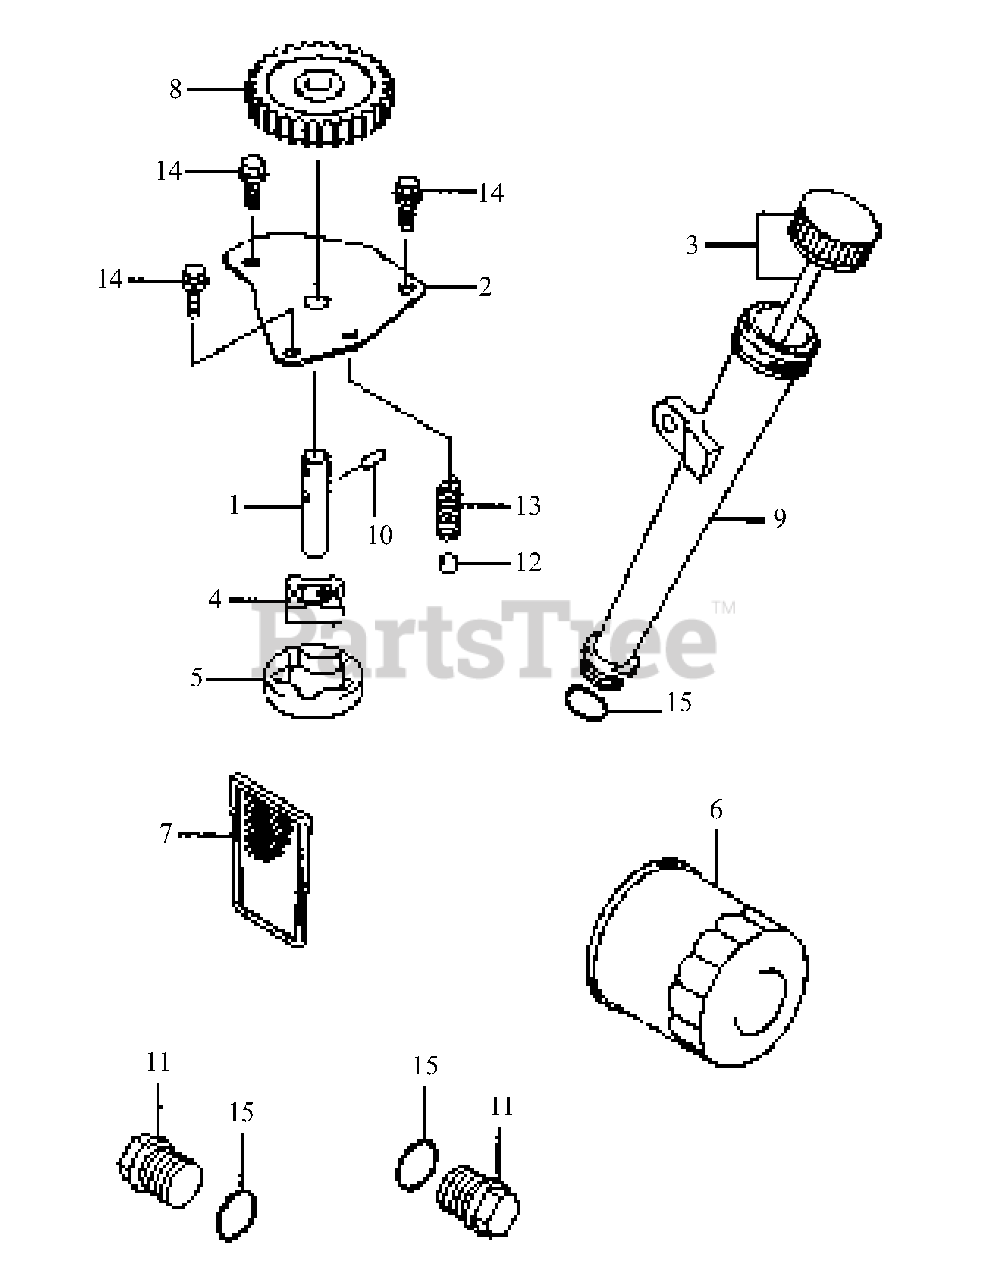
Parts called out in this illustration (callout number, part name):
1	Shaft, Oil Pump
3	Cap, Assembly
4	Rotor, Pump In
5	Rotor, Pump Out
6	Filter, Oil
7	Filter, Oil Screen
8	Gear, Spur
10	Pin
11	Plug
14	Bolt, Flange
